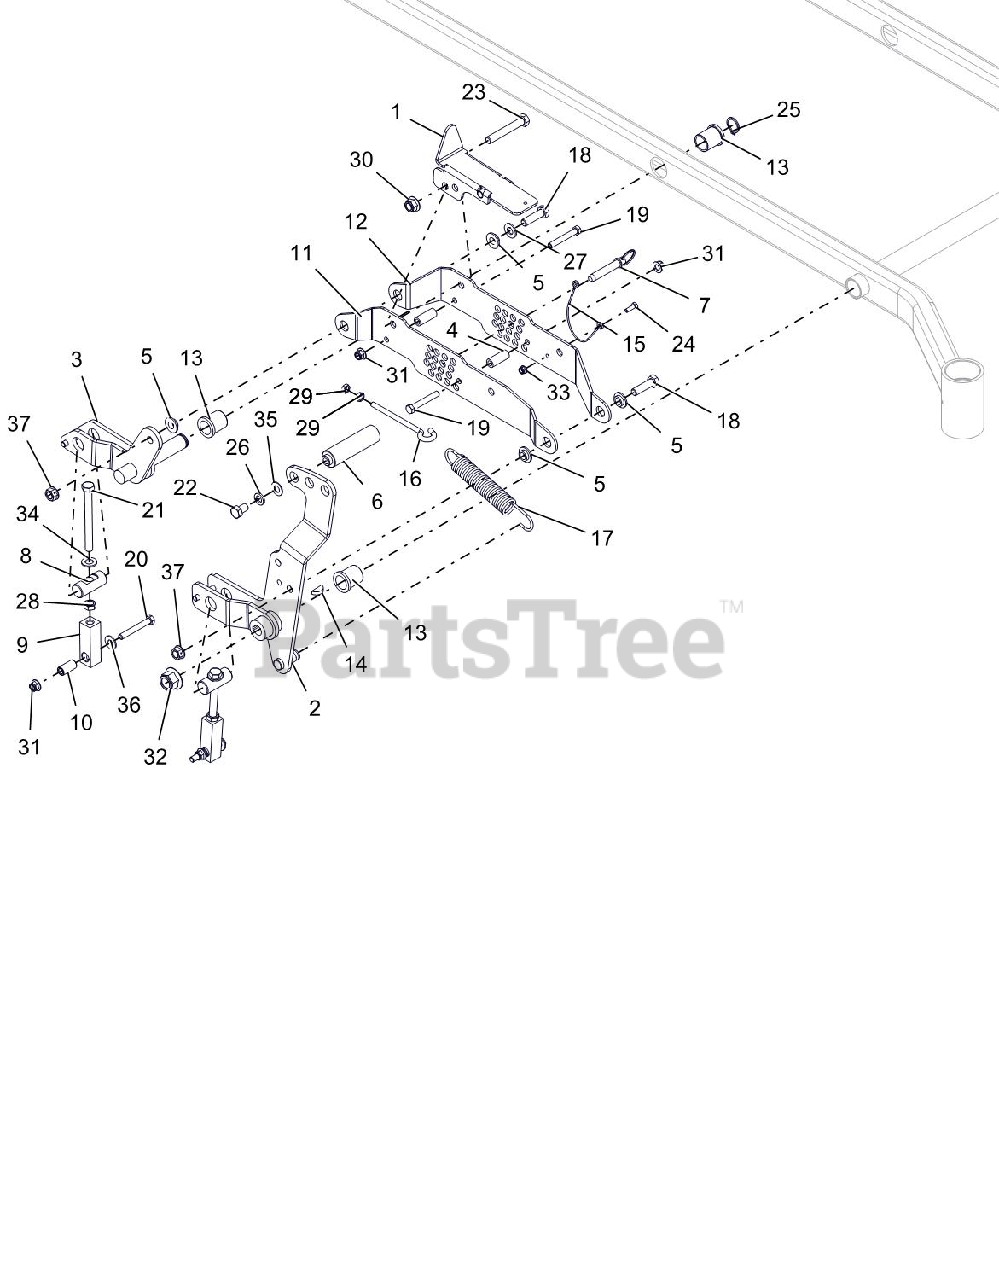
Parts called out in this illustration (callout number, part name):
1	WLDMT, MECHANICAL LOCK-UP-BLACK
2	WLDMT, FRONT RH DECK LIFT ARM (BLACK)
3	WLDMT, REAR RH DECK LIFT ARM (BLACK)
4	SPACER, .375 X .625 X 1.54
5	BSHG, FLANGE .515X.750X.31X1.12
6	PEDAL, LIFT
7	PIN, .500 x 2.000 USABLE LG BALL
8	PIN, DECK LIFT
9	LINK, DECK LEVELING
10	SPCR, DECK LEVELING
11	BRKT, RH OUTBOARD LIFT/CUT HEIGHT
12	BRKT, RH INBOARD LIFT/CUT HEIGHT (BLACK)
13	BSHG-FLG 1.00X1.25X1.5X1.5
14	KEY, WDRF .25 X 1.00 HRD #15
15	LANYARD, 12"
16	BOLT, EYE .38-16X6.00 .62 DIA
17	SPRG, TENSION .162 X 1.250 X 8.250
18	BOLT, HEX 0.5-13X1.75 GR5
19	BOLT, HEX 0.375-16X2.5 GR5
20	BOLT, HEX 0.375-16X2.75 GR8
21	BOLT, HEX 0.5-13X5 GR5
22	BOLT, HEX 0.5-13X0.75 GR5
23	BOLT, HEX 0.5-13X3.25 GR5
24	BOLT, HEX 0.25-20X0.75 GR5
25	RG-RTNG-EXT 1.00X.078
26	WSHR-LK .50X.125 REG YWZC
27	WSHR-FL-STL .531X1.062X.095 ZC120
28	NUT, JAM .500-13 YWZC
29	NUT, JAM .375-16 YWZC
30	NUT-LK-NYL-FLG .50-13 YWZC
31	NUT-LK-NYL-FLG .38-16 YWZC
32	NUT-LK-NYL-FLG .75-10 YWZC
33	NUT-LK-NYL-FLG .25-20 YWZC
34	WSHR-FL-STL .557X1.040X.102 YWZC HARD
35	WSHR-FL-STL .505X1.00X.062 YWZC
36	WSHR-FL-STL.438X1.00X.083 YWZC
37	NUT-LK-CTR-FLG .50-13 YWZC
